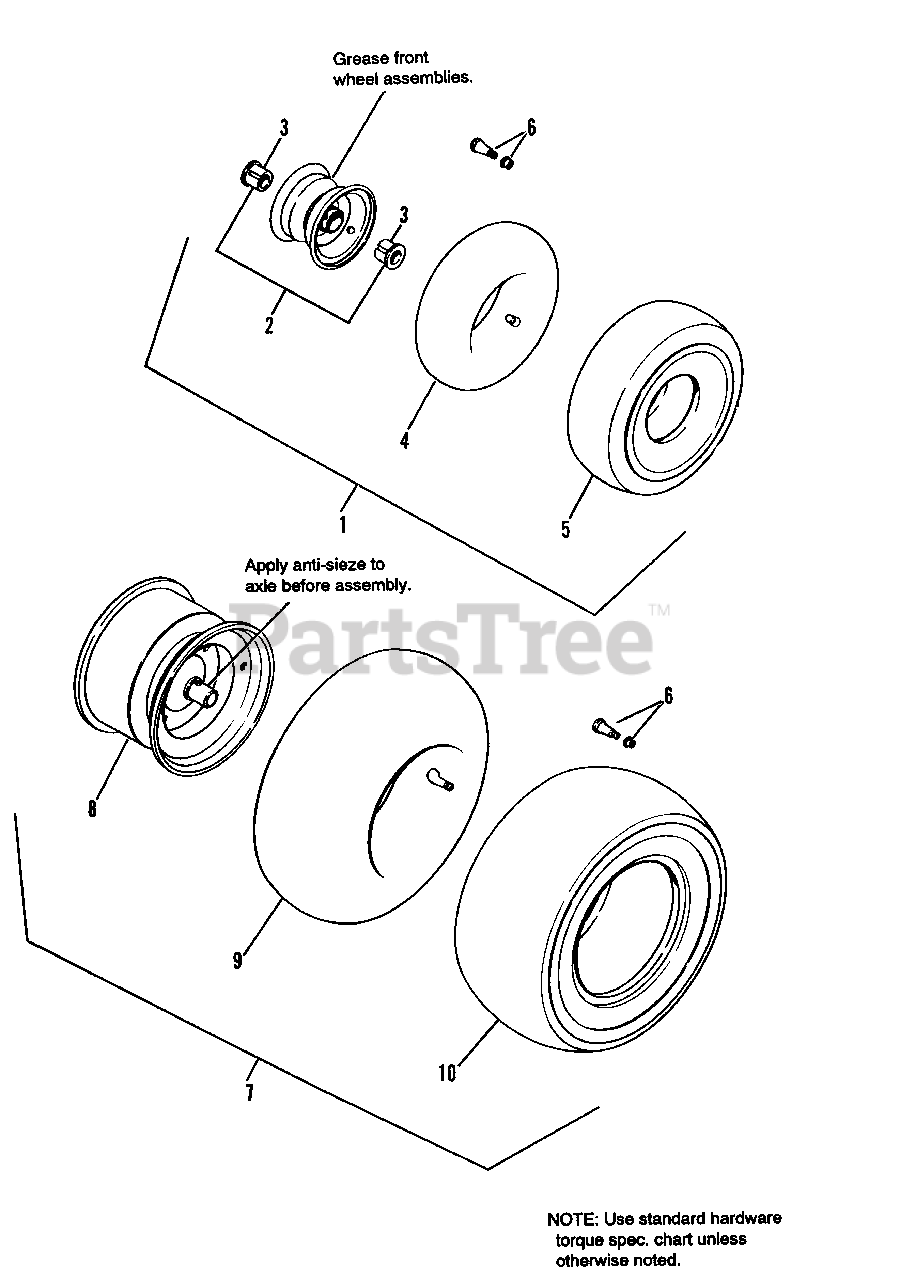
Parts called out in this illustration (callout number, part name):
1	FRONT WHEEL & TIRE ASSY., White (13 x 5.00-6) (Incl. Ref. Nos. 2,3, 4,5 & 6)
1	FRONT WHEEL & TIRE ASSY., White (13 x 5.00-6) (Includes Ref. Nos. 2, 3, 4, 5 & 6)
2	FRONT WHEEL ASSY., White, (13 x 5.00-6) (Incl. Ref. No. 3)
2	FRONT WHEEL ASSY., White, (13 x 5.00-6) (Includes Ref. No. 3)
3	BUSHING, Metal (7-21/32 I.D.)
3	BUSHING, Plastic (7-21/32 I.D.)
4	TUBE (4.10/3.50 x 6)
5	TIRE (13 x 5.00-6)
6	VALVE STEM & CAP
7	REAR WHEEL & TIRE ASSY., White (16 x 6.50-8) (Incl. Ref. Nos. 6, 8, 9 & 10)
7	REAR WHEEL & TIRE ASSY., White (16 x 6.50-8) (Includes Ref. Nos. 6, 8, 9 & 10)
8	REAR WHEEL ASSY., White
10	TIRE (16 x 6.50-8)
